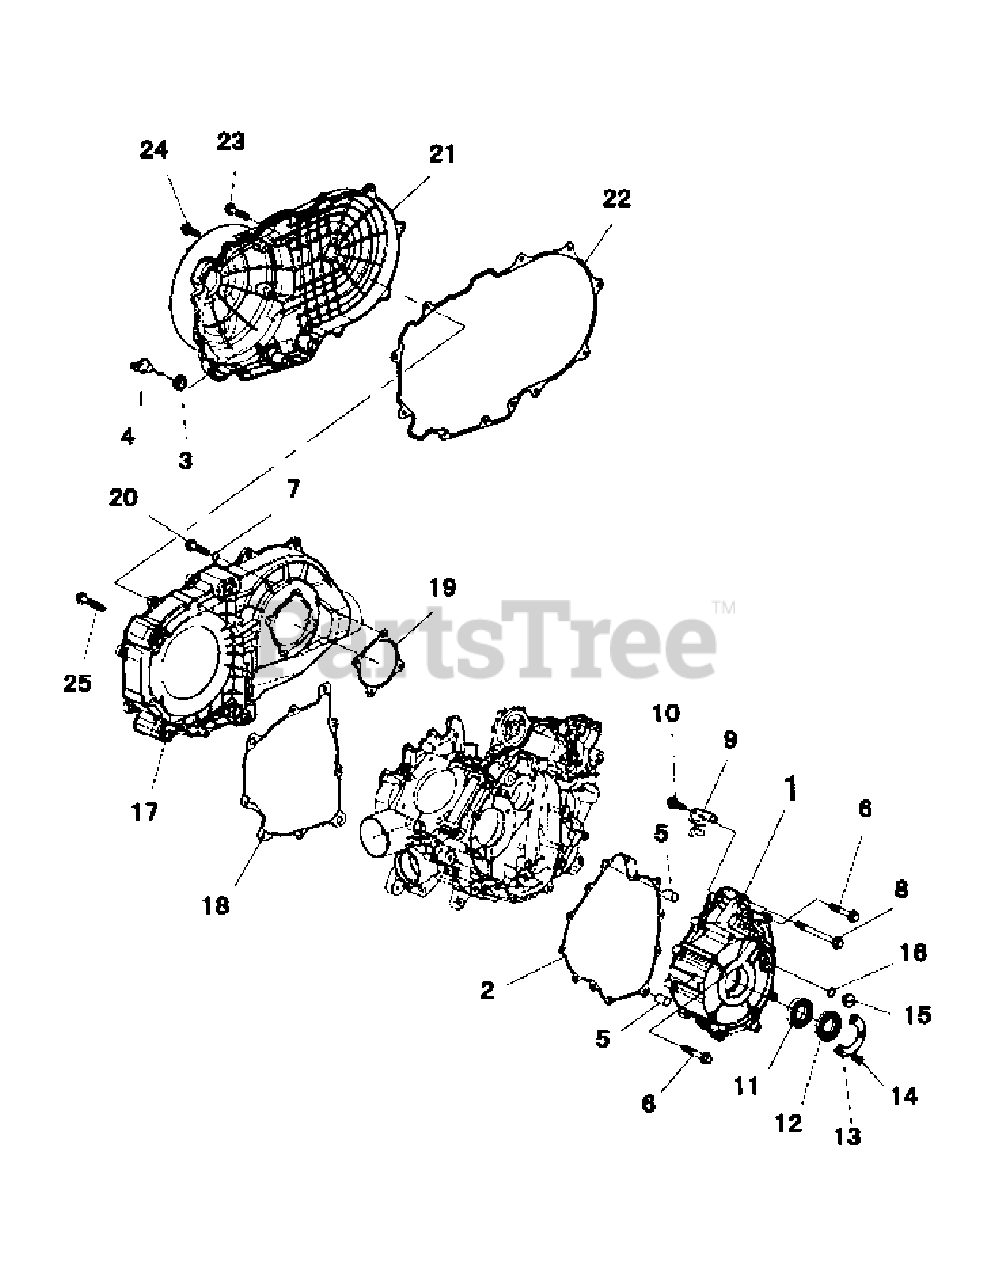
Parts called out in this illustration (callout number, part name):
1	Cover-Left
2	Gasket,Leftfront
4	Piledhead,Clutchcover
6	Flangebolt M6X30
8	Flangebolt M6X40
9	Press Wire Plate -Stator
10	Flangebolt M6X12
12	Oil Seal
13	Pressure Plate-Left Front
15	Handholecover
16	O-Ring 13.4X2.35
17	Seat Cover-Compl Cloth
18	Gasket-Clutch Cover
19	Gasket-Clutch Cover
20	Flange Bolt M6X32
21	Covercomp,Cluth
22	Gasket-Clutchcover
23	Flange Bolt M6X25
24	Flangebolt M6X16
25	Flange Bolt M6X50
